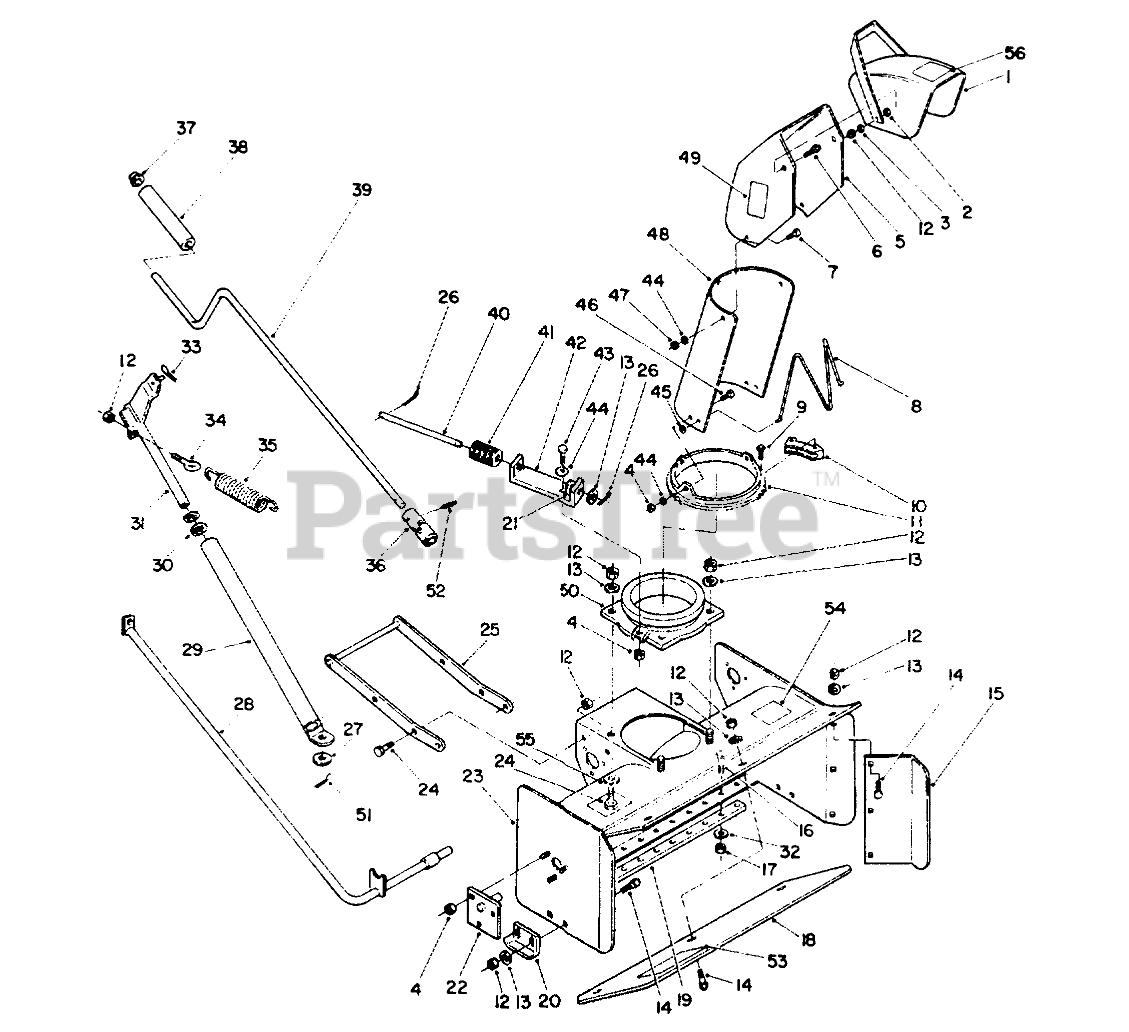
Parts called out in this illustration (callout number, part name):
1	Defector (Incl. ref. #56)
2	WASHER-RUBBER
3	WASHER-BELLEVILLE
4	NUT-LOCK, NI
5	Chute-Upper
6	BOLT-CARR
7	SCREW-HH
8	WIRE-CHUTE
9	SCREW-SPECIAL
10	RETAINER-CHUTE
11	Ring-Swivel
12	NUT-LOCK, NI
13	WASHER-FLAT
14	BOLT-CARR
15	Plate
16	SCREW-CARR
17	NUT-LOCK, NI
18	Plate
19	Scraper
20	Skid
21	WASHER-SPRING
22	Plate
23	Wrapper
24	SCREW-HH
25	Frame-Mounting
26	PIN-COTTER
27	WASHER-FLAT
28	Crank Support
29	Lift Tube
30	WASHER-FLAT
31	LIFT ROD ASM
32	WASHER-FLAT
33	Hairpin Cotter
34	EYEBOLT
35	SPRING
36	Universal
37	RETAINER-PUSH ON
38	GRIP-CONTROL, CHUTE
39	ROD-CHUTE CONTROL
41	GEAR-WORM, CHUTE
42	Bracket-Worm
43	BOLT-CARR
44	WASHER-PLAIN
45	NUT-PUSH
46	CARRIAGE BOLT -4
47	NUT-LOCK, NI
48	Chute-Extender
49	Decal-Danger
50	Adapter
51	PIN-COTTER
52	PIN-SPRING
53	DECAL - REAR FRAME
54	DECAL-WARNING, AUGER
55	SPACER
56	Decal-Danger
